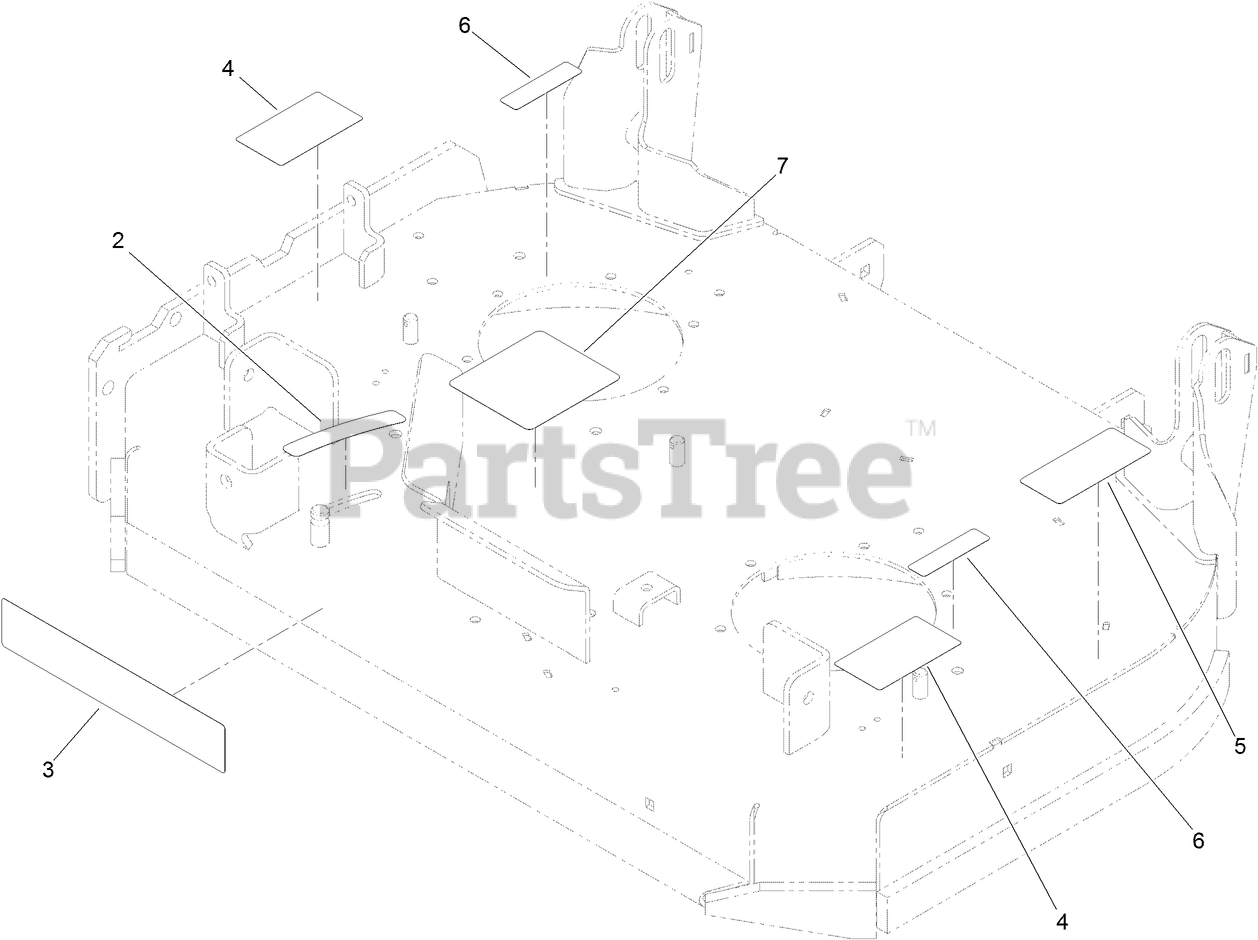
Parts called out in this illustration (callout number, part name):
2	DECAL-SETTING, BAFFLE
4	DECAL-DANGER
5	DECAL-TORQUE, BLADE BOLT
6	DECAL-DANGER
7	DECAL-ROUTING, BELT
